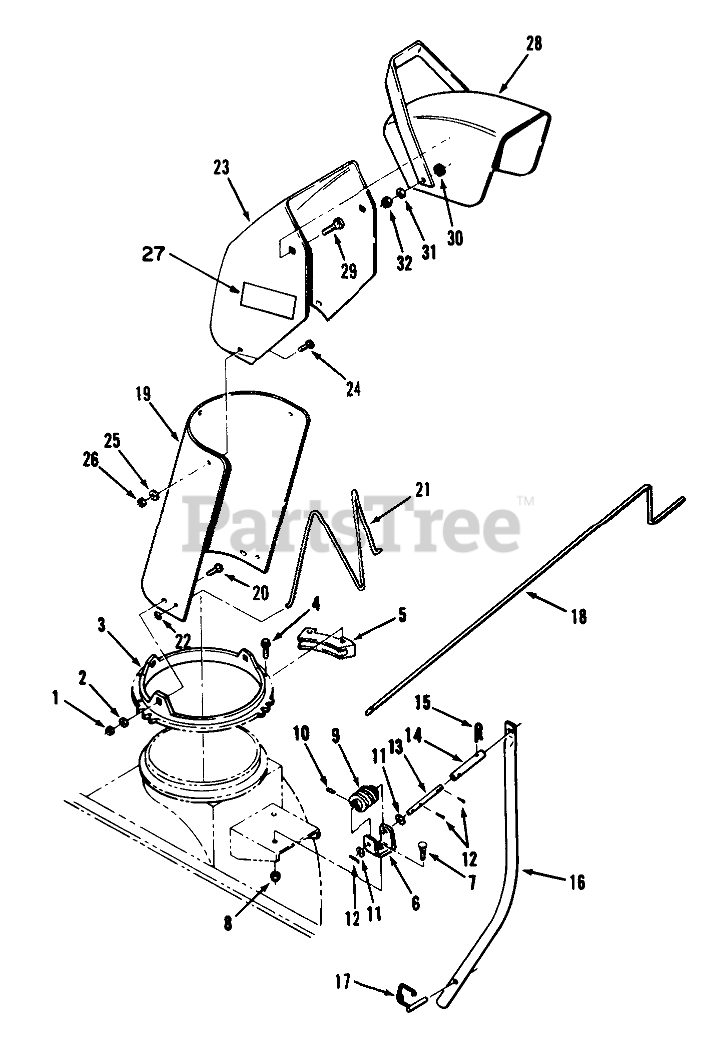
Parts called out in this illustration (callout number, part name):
1	NUT-LOCK, NI
2	WASHER 5/16 SAE
3	Screw
4	SCREW-SPECIAL
5	RETAINER-CHUTE
6	WORM BRKT B
7	BOLT-CARR
8	NUT-LOCK, NI
9	GEAR-WORM, CHUTE
10	Pin-Roll
11	WASHER-FLAT
12	Pop Rivet
13	ROD-LOWER CHUTE CONT
14	COUPLING
15	Hairpin Cotter
16	TUBE-CRANK SUPPOR R
17	LOCKING PIN ASM
18	ROD-CHUTE CONTROL
19	Chute-Extender
20	SCREW-HH
21	WIRE-CHUTE
22	NUT-PUSH
23	Chute-Upper
24	CARRIAGE BOLT -4
25	WASHER 5/16 SAE
26	Nut
27	DECAL DANGER
28	Deflector
29	BOLT-CARR
30	WASHER-RUBBER
31	WASHER-BELLEVILLE
32	NUT-LOCK, NI
